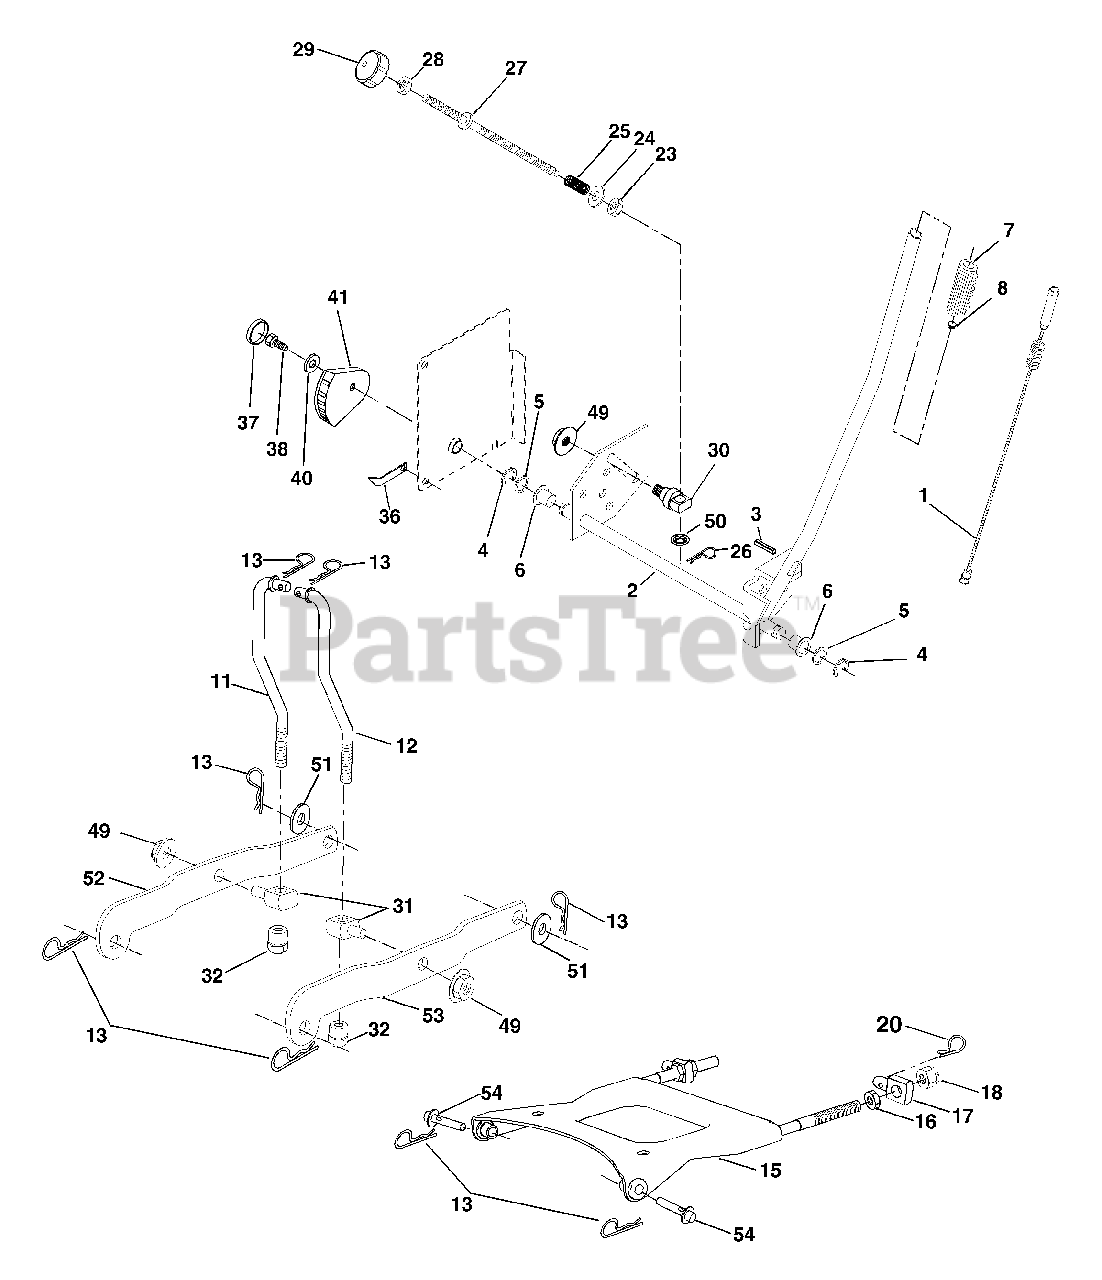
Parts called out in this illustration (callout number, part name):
1	Wire Asm Inner/Spring W/Plunger LT
2	Shaft Asm Lift RH w/Inf
3	Pin Groove 1 500 Zinc
4	E Ring #5133-62
5	Washer 21/32 X 1 X 21 Ga
6	Bearing Nylon Blk 629 Id
7	Grip Handle Fluted Blk
8	Button Plunger Black
11	Link Lift LH
12	Link Lift RH
13	Retainer Spring
15	Plate Asm Susp Front
16	Nut Jam Hex 1/2-13 Unc
18	Nut Lock w/Wsh 1/2-13unc
20	Retainer Spring
23	Nut Special
24	Washer 13/32 X 5/8 X 16 Ga
25	Spring 2-1/8"
26	Retainer Clip
27	Rod Adj Lift Zinc 7.49 Wrk Lg
28	Nut Hex Jam 3/8-16 Unc
29	Knob Inf 3/8-16 Unc Blk W/sym
30	Trunnion Infin Height
32	Nut Lift Link 7/16-20
36	Indicator Height STLT
37	Plug Hole Blk 1.485/1.515 Dia.
38	Screw 5/16-18 x 1
40	Washer 11/32 x 1-1/2 10 Ga.
41	Scale Ind. Height Blk.
49	Nut Hex Flange Lock
50	Nut, Push Phos & Oil
51	Washer 17/32 x 7/8 x 16 Ga.
52	Arm Susp. Rear Lh
53	Arm Susp. Rear Rh
54	Pin Flange
